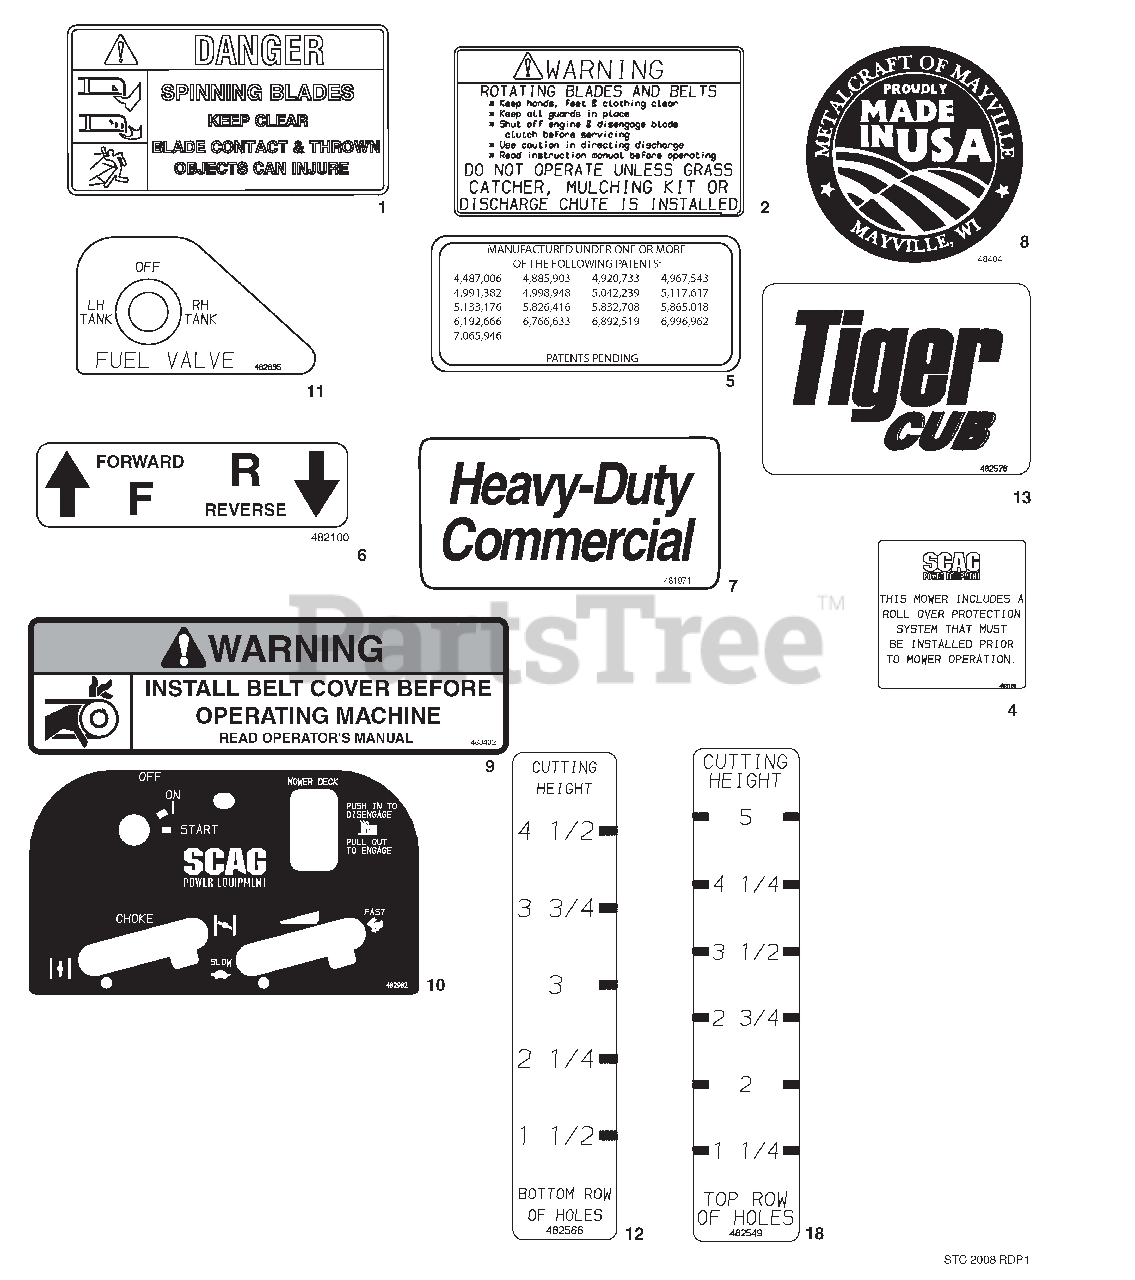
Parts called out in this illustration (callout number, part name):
1	Decal, Danger-Spinning Blades
2	Decal, Warning-Rotating Blades
4	Decal, ROPS
5	Decal, Patents
6	Decal, Traction Control
7	Decal, Heavy Duty Commercial
8	Decal, Metalcraft - Made in USA
9	Decal, Belt Cover
10	Decal, Instrument Panel
11	Decal, Fuel Valve Position
12	Decal, Cutting Height Bottom Row of Holes
13	Decal, Tiger Cub
18	Decal, Cutting Height Top Row of Holes
